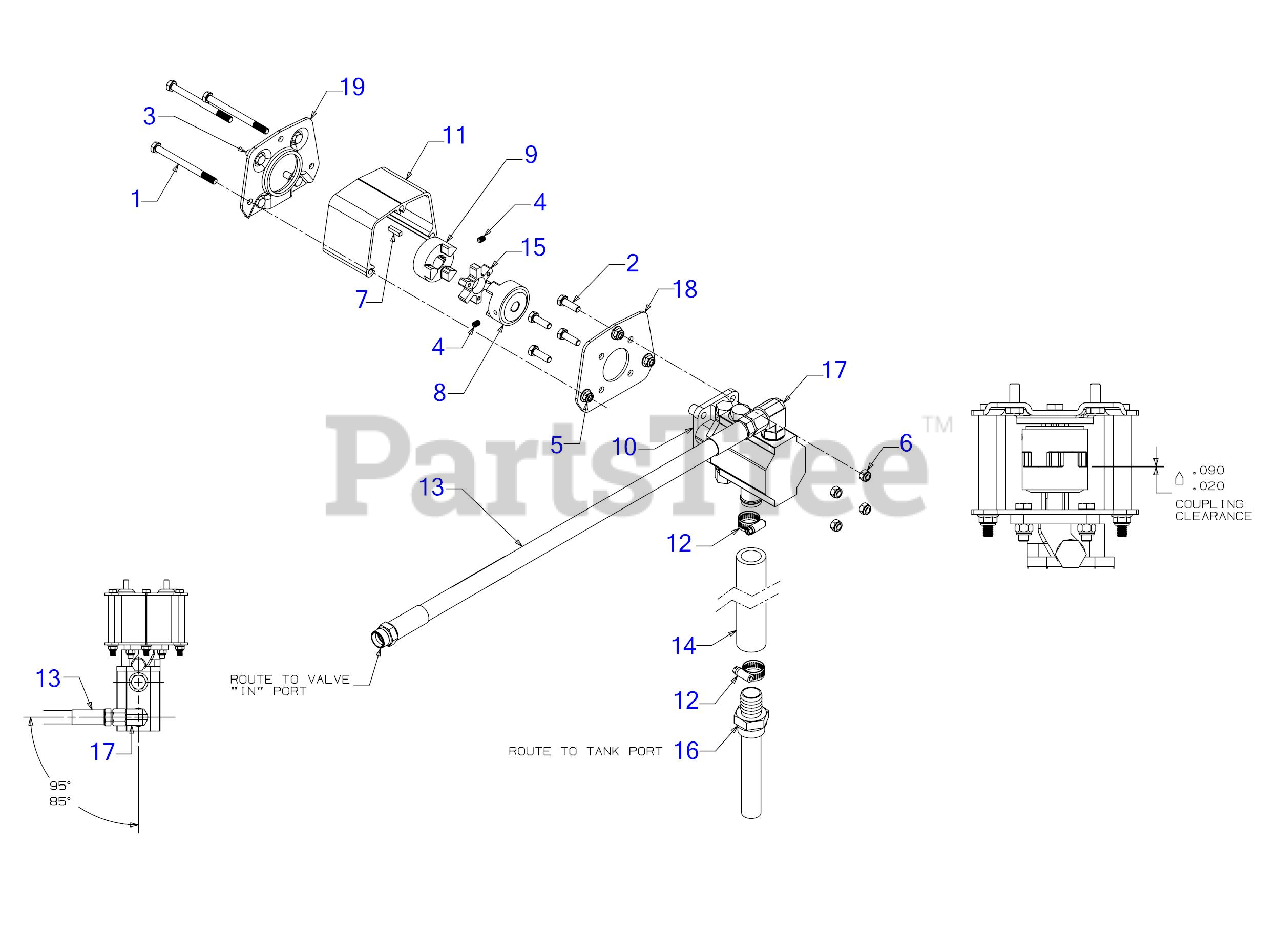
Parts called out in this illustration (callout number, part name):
1	HEX SCREW 5/16-18 x 4.00
2	SCREW 5/16-18 x 1.0 GR5
3	SCREW 5/16-24 x .750 GR5
4	SCREW 1/4-20 x .38
5	FLANGE LOCK NUT 5/16-18
6	HEX NUT
7	SQUARE KEY 3/16 x .7
8	LOGSPLITTER COUPLING .500
9	LOGSPLITTER COUPLING .750
10	GEAR PUMP 15 GPM
11	COUPLING SHIELD
12	HOSE CLAMP-5/8
13	48" HYDRAULIC HOSE
14	INPUT HOSE
15	SPIDER COUPLING BUSHING
16	INLET FILTER
17	90 DEGREE HYDRO FITTING 7/8 ORB x 13/16
18	SUPPORT BRACKET
